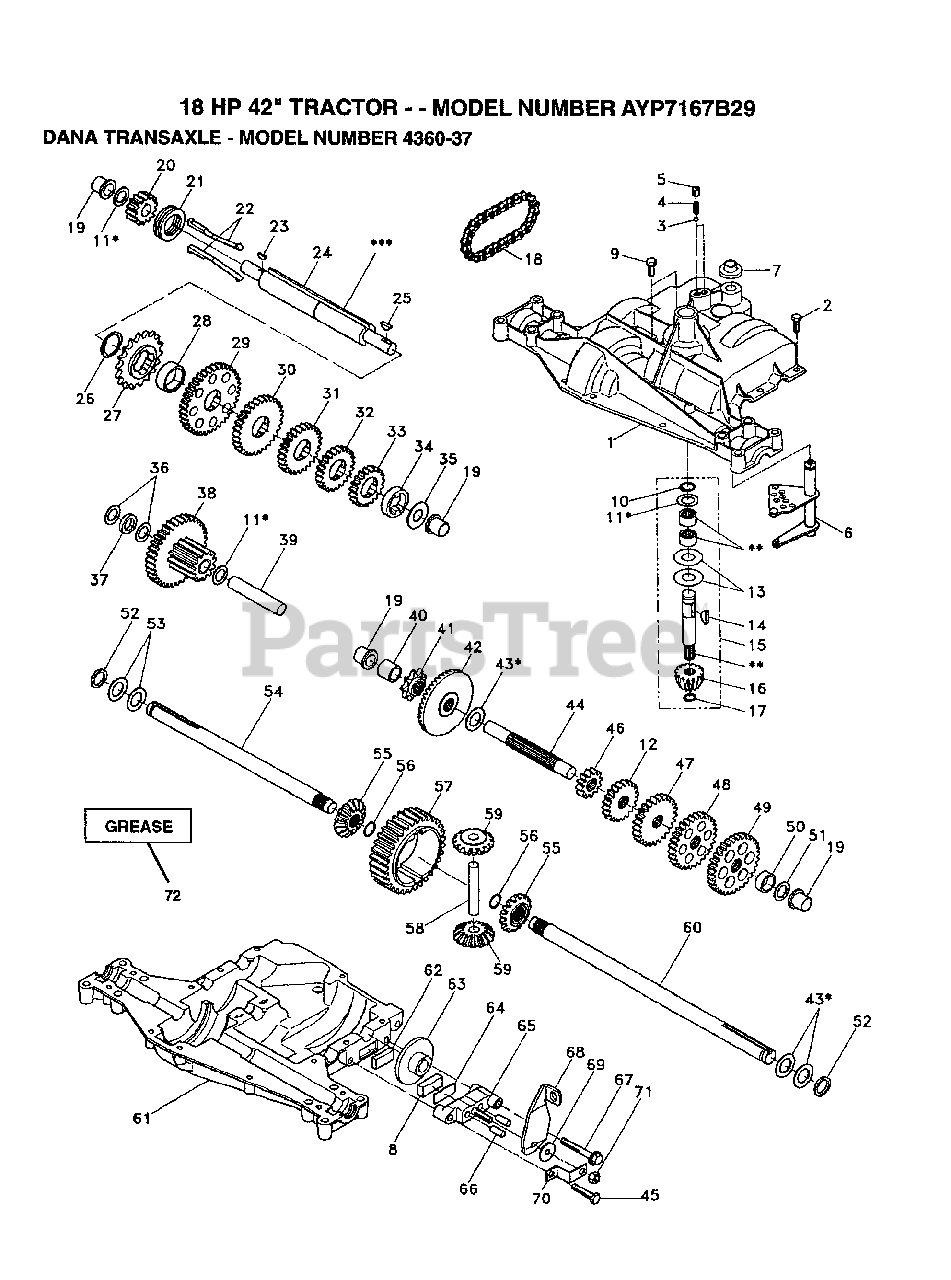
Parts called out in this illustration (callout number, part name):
1	HOUSING UPPER
3	BALL, DETENT
4	SPRING, DETENT
5	SCREW, SET
6	KIT, SHIFTER ASSEMBLY
7	BOOT, SHIFTER
8	PUCK, FRICTION
9	SCREW TAPPING WITH SEALER
10	RING RETAINING
11	ASSY, KIT, SHIM .625 SHAFT
12	GEAR SPUR, 15 TEETH
13	WASHER, PLAIN .632 X 1.38 X .046
14	KEY WOODRUFF #9
15	ASSY KIT INPUT SHAFT
16	PINION BEVEL 14 TEETH
17	RING, RETAINING
18	CHAIN, 24 PITCHES
19	BEARING, FLANGE
20	GEAR SPUR, 14 TEETH
21	COLLAR CLUTCH
22	KEY CLUTCH
23	KEY WOODRUFF #3
24	SHAFT INTERMEDIATE
25	KEY, WOODRUFF, #61
26	RING, RETAINING
27	SPROCKET, 18 TEETH
29	GEAR, SPUR, 37 TEETH
30	GEAR, SPUR, 35 TEETH
31	GEAR, SPUR, 30 TEETH
32	GEAR, SPUR, 25 TEETH
33	GEAR, SPUR, 22 TEETH
34	GEAR, SPUR, 19 TEETH
35	WASHER, PLAIN .640 X 1.37 X .061
36	WASHER, PLAIN .632 X 1.00 X .026
37	SPACER .630 X 1.00 X .169
38	ASSY GEAR COMB 12&35 TEETH
39	SHAFT, IDLER
40	SPACER .635 X .875 X .755
41	SPROCKET, 9 TEETH
42	GEAR, BEVEL, 42 TEETH
43	ASSY, KIT, SHIM .750 SHAFT
44	SHAFT, DRIVE
45	SCREW TAPPING
46	GEAR, SPUR, 12 TEETH
47	GEAR, SPUR, 20 TEETH
48	GEAR, SPUR, 25 TEETH
49	GEAR, SPUR, 28 TEETH
50	GEAR, SPUR, 31 TEETH
51	WASHER, PLAIN .632 X 1.00 X .060
52	WASHER, NEOPRENE
53	WASHER, PLAIN .758 X 1.25 X .031
54	AXLE LEFT HAND
55	GEAR MITER 15 TEETH
56	RING, RETAINING
57	GEAR, SPUR, 32 TEETH
58	SHAFT, CROSS
59	GEAR, MITER, 15 TEETH
60	AXLE, R.H.
61	HOUSING LOWER
62	PUCK, FRICTION
63	DISC, BRAKE
65	JAW, BRAKE
66	PIN, DOWEL
67	SCREW, SELF-TAPPING
68	LEVER, ACTUATING
69	WASHER, PLAIN .321 X 1.00 X .055
70	BRACKET, ANTI-ROTATION
71	LOCKNUT 5/16-24
